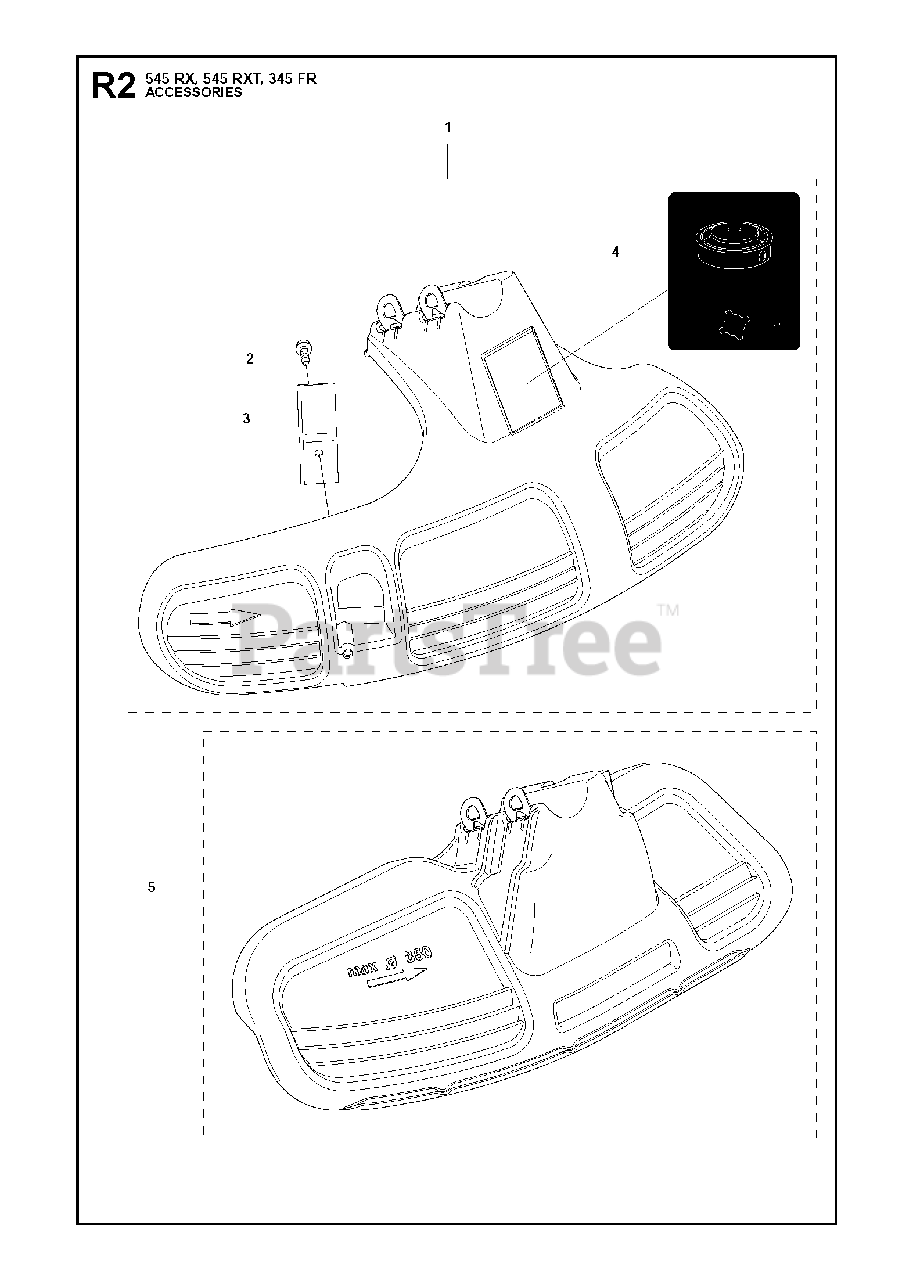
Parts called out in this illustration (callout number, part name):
1	BLADE GUARD
2	SCREW
3	LINE CUTTER
4	DECAL
5	BLADE GUARD
